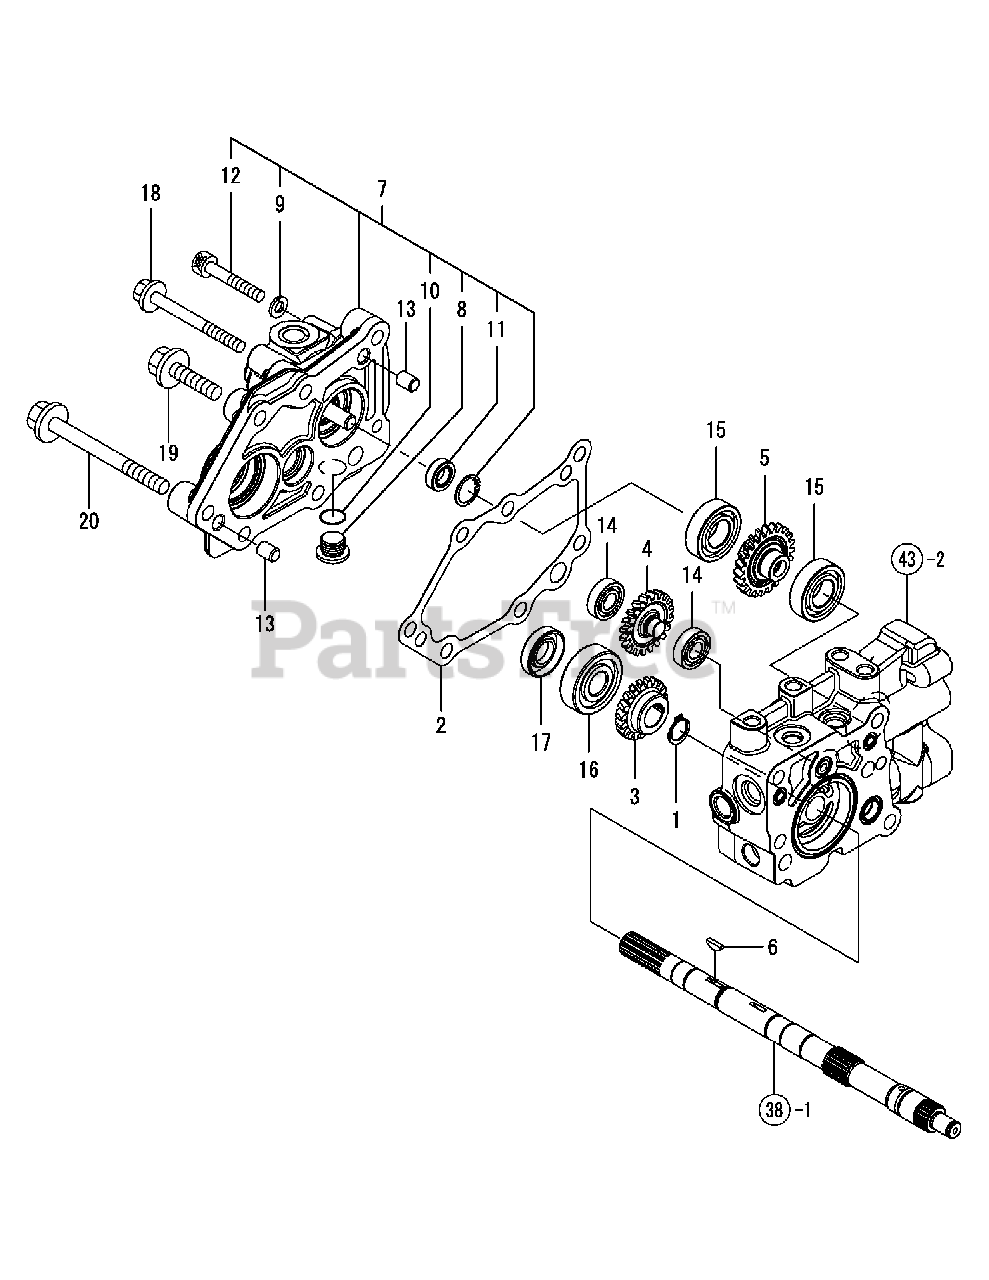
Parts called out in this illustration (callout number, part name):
2	PAKING (PUMP COVER
7	PWS-5CG SUB CMP
10	O-RING 1A P-14.0
11	SEAL TC12 22 07, OIL
13	PARALLEL PIN, M10X12
15	BALL BEARING #6004
16	BALL BEARING
17	SEAL TC17 35 08, OIL
20	BOLT W/WASHER 10x105
